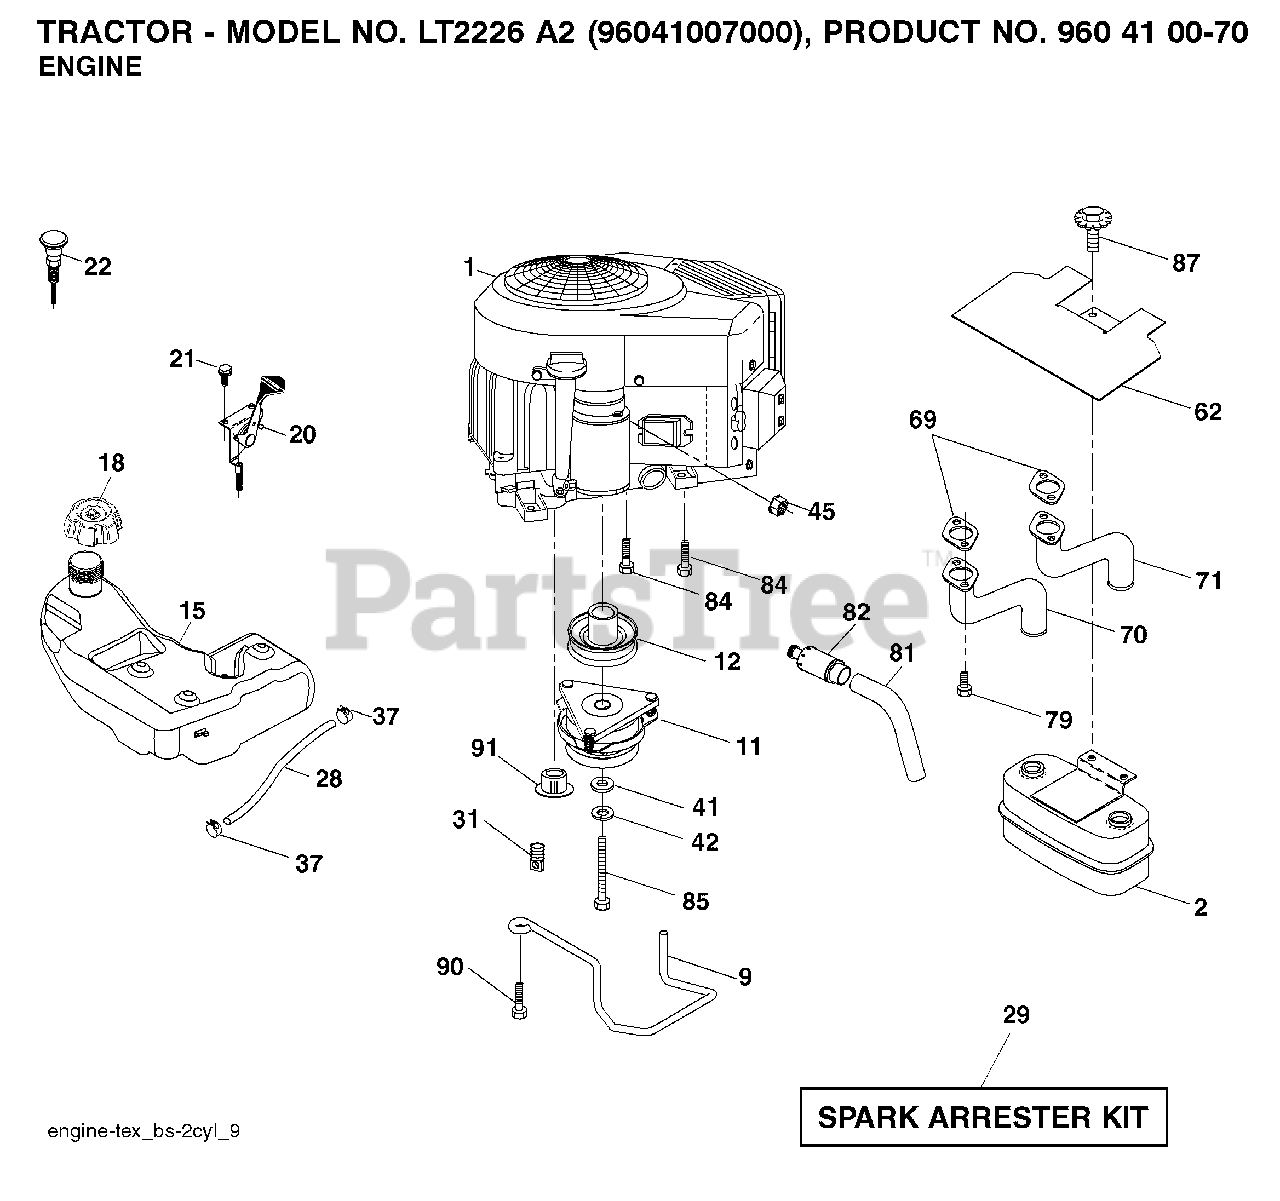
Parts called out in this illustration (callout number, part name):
2	MUFFLER.TWIN.CYL.LOW.TONE
9	KEEPER.BELT.ENGINE.4.2
11	CLUTCH
12	PULLEY.ENGINE.TUFFTORQ
15	TANK.FUEL.4GAL
18	CAP.ASM.FUEL.TANK.3"BL
20	THROTTLE CABLE
21	SCREW.#10 X 0.750.BOS THREAD
22	CONTROL CHOKE
29	ARRESTER SPARK (OPTIONAL)
31	PUSH CLIP
37	HOSE CLAMP
42	LOCKWASHER
45	NUT
62	RP SHIELD HEAT MUFFLER
69	GASKET.MUFFLER
70	TUBE MANIFOLD LH
71	EXHAUST TUBE RH
79	SCREW.SOCKET.HEAD.5/16-18
81	TUBE, DRAIN OIL ASM.
82	PLUG DRAIN OIL EASY
84	SCREW.3/8-16
85	BOLT HEX 7/16-20X4-1/4"
87	BOLT.5/16-18UNCX1.W/SEMS.BLK
90	SCREW 3/8-16X1
91	BUSHING.1.375OD
